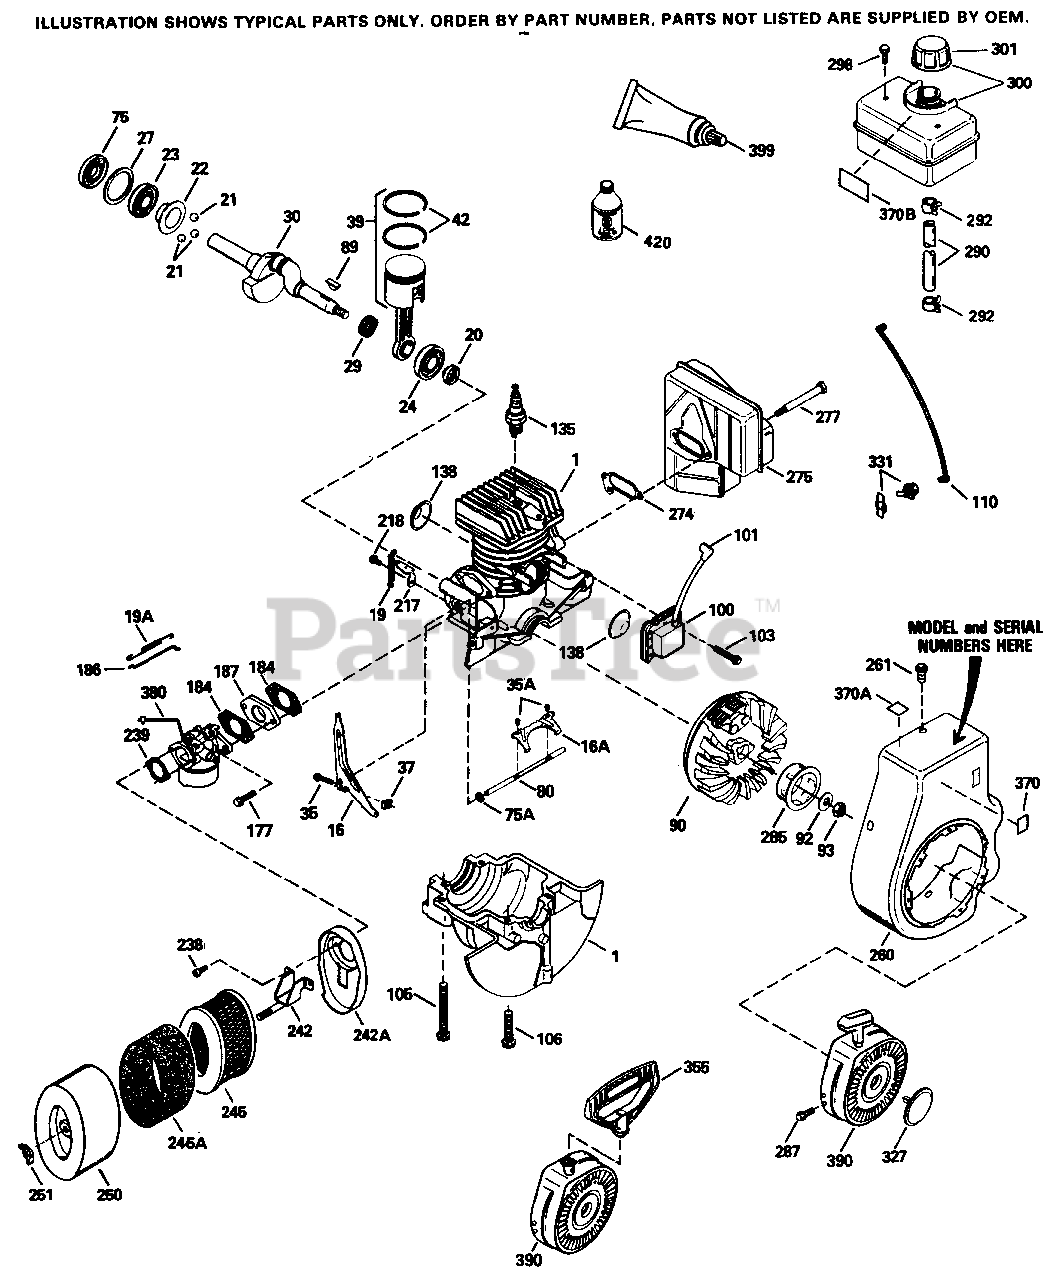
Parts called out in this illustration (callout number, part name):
1	"CYLINDER 06,138)
16	Governor Lever
16A	Governor Follower Arm
19	Governor Spring
19A	Backlash Spring
20	Oil Seal (Flywheel end)
22	Slide Ring
23	Ball Bearing (PTO end)
24	Ball Bearing (Magneto end)
27	Bearing Retainer
28	Oil Seal (PTO end)
29	Bearing Strip (31 needles)
30	Crankshaft
35	Screw, 10-32 x 3/4"
37	Lock Nut, 10-32
39	Piston & Rod Assy. (Incl. 29 & 42)
42	Piston Ring Set
64	Muffler Screw, 5/16-18 x 3-13/64"
75	Oil Seal
80	Governor Shaft
89	Flywheel Key
90	Flywheel
92	Belleville Washer
93	Flywheel Nut
100	Solid State Assy. (Incl. 101)
101	Spark Plug Cover
103	Screw, 10-24 x 1"
105	Screw, 5/16-18 x 2-3/16"
106	Screw, 5/16-18 x 1-5/8"
110	Ground Wire
135	Spark Plug (RCJ8Y)
138	Port Cover
163	Screw, 4-40 x 1/4"
177	Screw, 1/4-20 x 1"
184	Carburetor Gasket
186	Governor Link
187	Carburetor Spacer
217	Speed Control Lever
218	Screw, 8-32 x 1/2"
222	Screw, 10-32 x 1/2"
239	Filter Base Gasket
241	Air Cleaner Bracket
242	Air Cleaner Base Bracket
245	Air Filter (Paper) also available in Packaged Part #740027B
246	Poly Pre-Filter (also available in Pa ckaged Part #740027B)
250	Air Cleaner Cover
251	Wing Nut, 1/4-20
260	BLOWER HSG
261	Screw, 5/16-18 x 5/8"
269	Muffler Gasket
275	Muffler
285	Starter Hub
287	Screw, 8-32 x 1/2"
290	Fuel Line (16" long)
292	Fuel Line Clamp
298	Screw, 1/4-15 x 7/8"
300	Fuel Tank (Incl. 292 & 301) (2 Quart)
301	Fuel Cap Assy.
327	Starter Plug
331	Toggle Switch
355	Starter Handle (Mitten Grip) (also av ailable in Packaged Part #740053B) ( Not included with replacement starter , must order separately)
370	Decal, Name
370A	Decal, Caution
370B	Decal, Fuel mix
380	Carburetor (Incl. 184) (Refer to Divi sion 5, Section A, page A1-40 or Fich e 27A, Grid F-5 for breakdown)
390	Rewind Starter Refer to Division 5, S ection C, page 34 or Fiche 27A, Grid G-9 for breakdown
399	Gasket Eliminator (Use as required)
422	2-Cycle Oil with Fuel Stabilizer - 8 oz.
